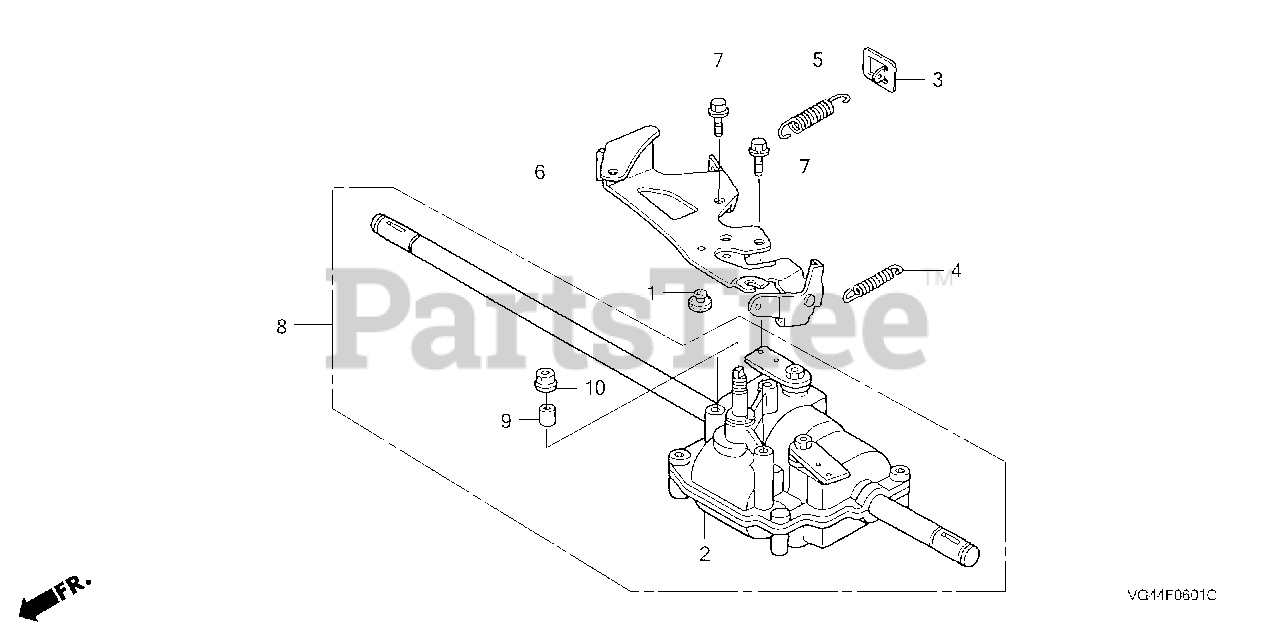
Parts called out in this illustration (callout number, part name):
1	RUBBER, STOPPER
2	TRANSMISSION ASSY. (N/A: USE TRANSMISSION KIT 06200-VG4-D00.)
3	PLATE, TENSION SPRING
4	SPRING, CLUTCH RETURN
5	SPRING, WHEEL TENSION
6	HOLDER, WIRE
7	BOLT, FLANGE (8X16)
8	TRANSMISSION KIT (3-SPEED)
9	COLLAR, INPUT (10.0X15.9X16.3)
10	NUT, FLANGE (10MM)
